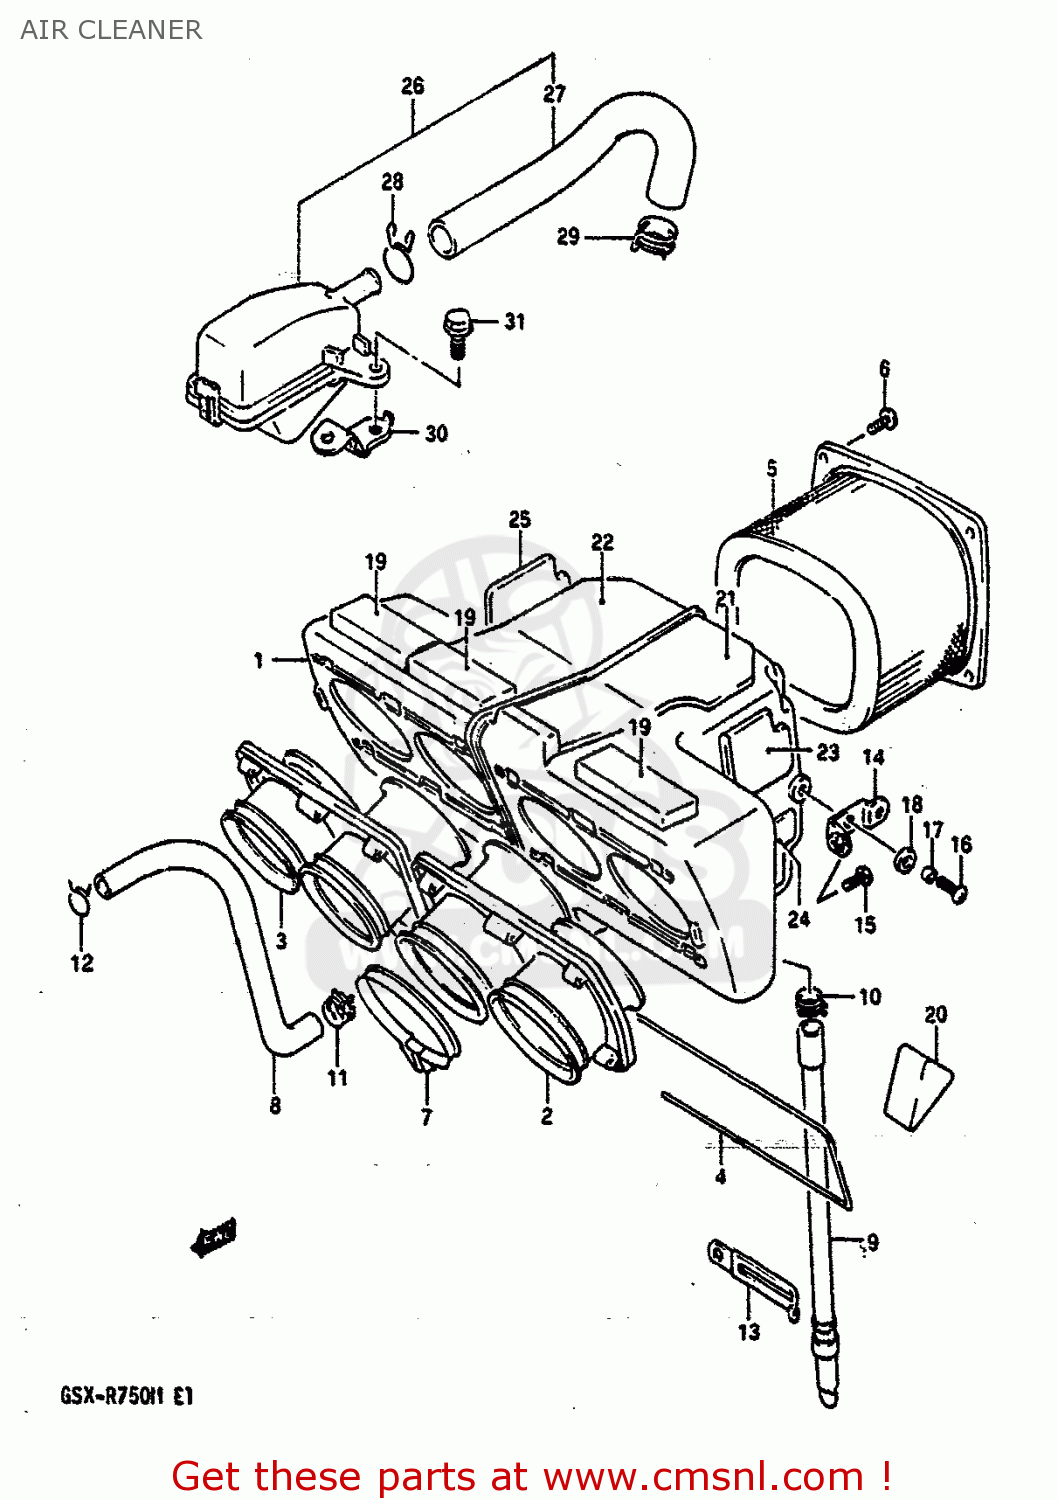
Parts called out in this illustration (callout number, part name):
1	CASE,AIR CLEANER
2	TUBE,OUTLET,L
3	TUBE,OUTLET,R
4	SHAFT,OUTLET TUBE
5	FILTER ASSY,AIR
6	SCREW
7	CLAMP
8	TUBE,BREATHER
9	DRAIN TUBE
10	CLIP
11	CLIP
12	CLIP
13	CLAMP
14	BRACKET,AIR CLEANER CASE
15	SCREW
16	SCREW(6X18)
17	SPACER
18	WASHER
19	CUSHION,AIR CLEANER CASE
20	CUSHION,AIR VENT HOSE
21	SHEET,AIR CLEANER NO.1
22	SHEET,AIR CLEANER NO.2
23	SHEET,AIR CLEANER NO.3
24	SHEET,AIR CLEANER NO.4
25	SHEET,AIR CLEANER NO.5
26	CLEANER ASSEMBLY,AIR
27	TUBE,2ND AIR CLEANER
28	CLIP
29	CLAMP
30	BRACKET,2ND AIR CLEANER
31	BOLT
